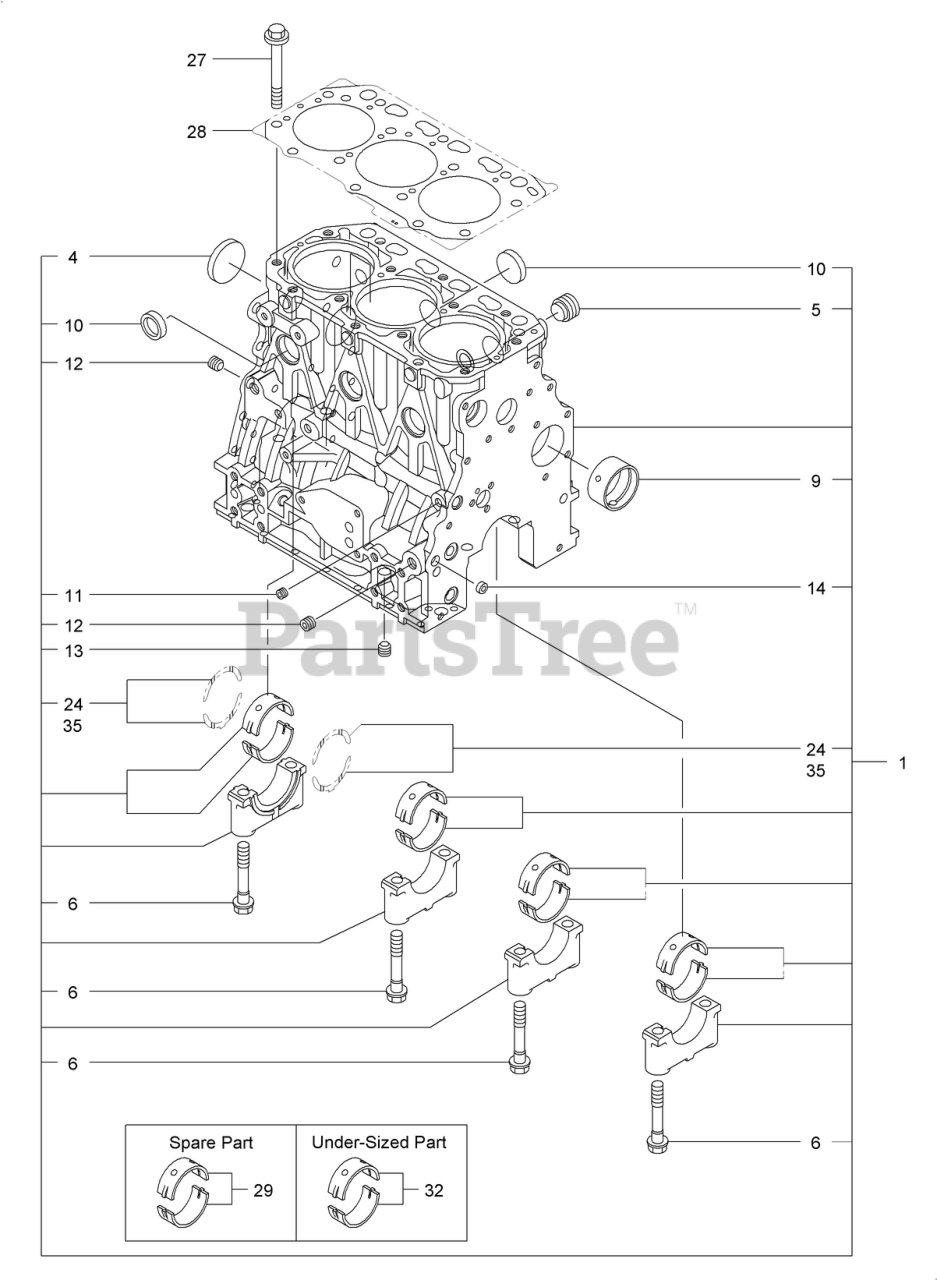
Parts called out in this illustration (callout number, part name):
1	CYLINDER BLOCK ASM
9	BUSHING
10	PLUG 30
24	METAL-THRUST
28	HEAD GASKET ASM
29	METAL-MAIN
32	METAL-MAIN (0.25)
35	METAL-THRUST (0.25)
